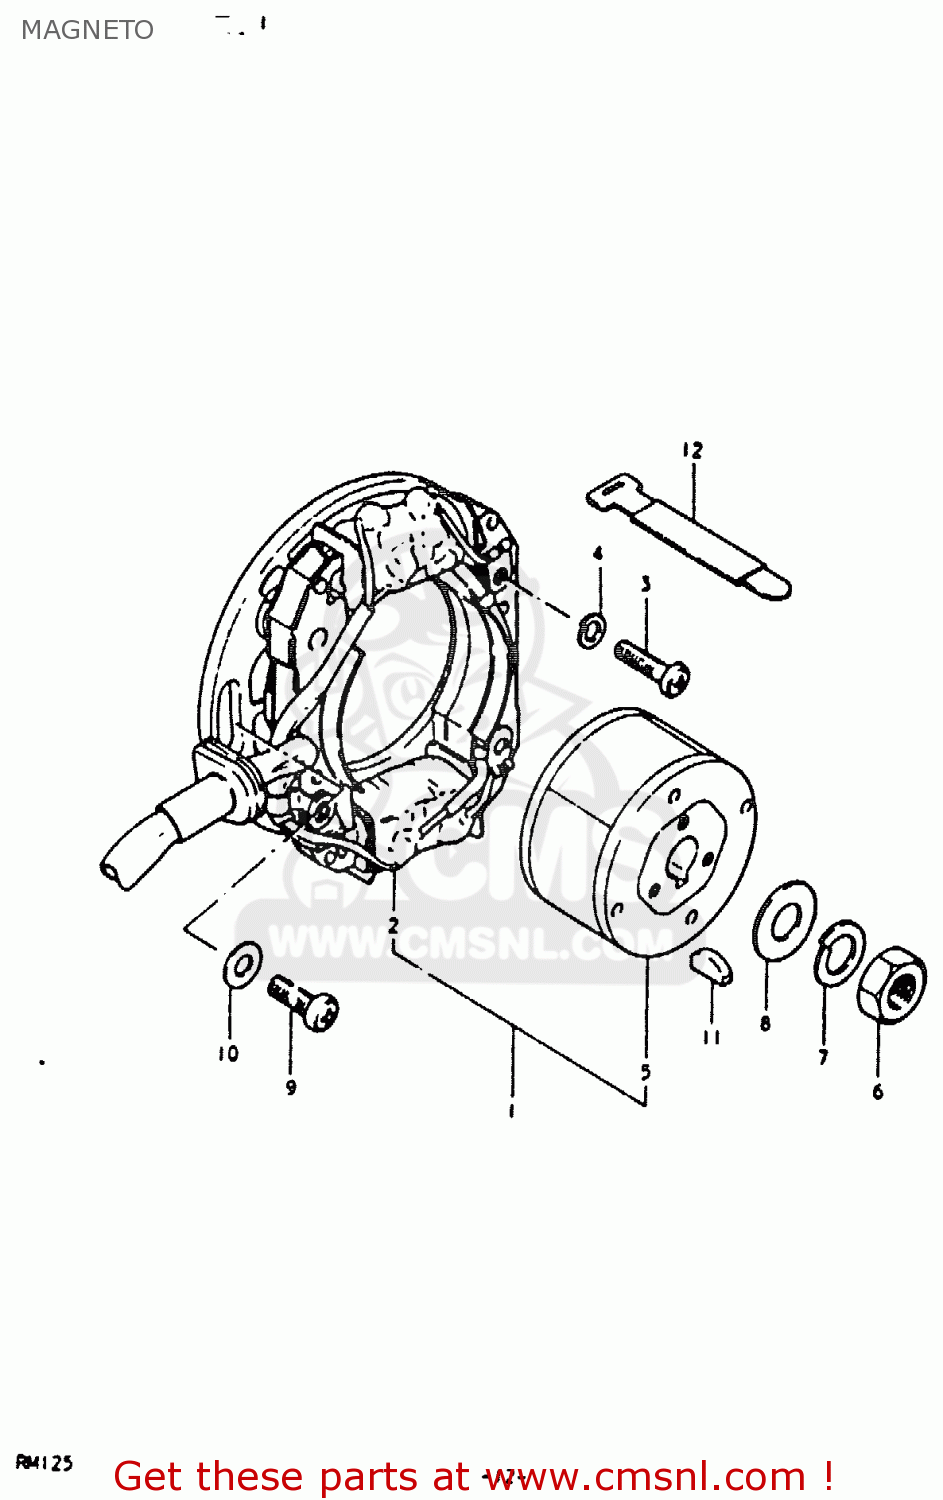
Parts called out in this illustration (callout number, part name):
1	MAGNETO ASSEMBLY
2	STATOR ASSEMBLY
3	SCREW 5X20
4	LOCK WASHER
5	ROTOR ASSEMBLY
6	NUT (10MM)
7	LOCK WASHER
8	WASHER
9	SCREW
10	WASHER
11	KEY 4MM
12	CLAMP
